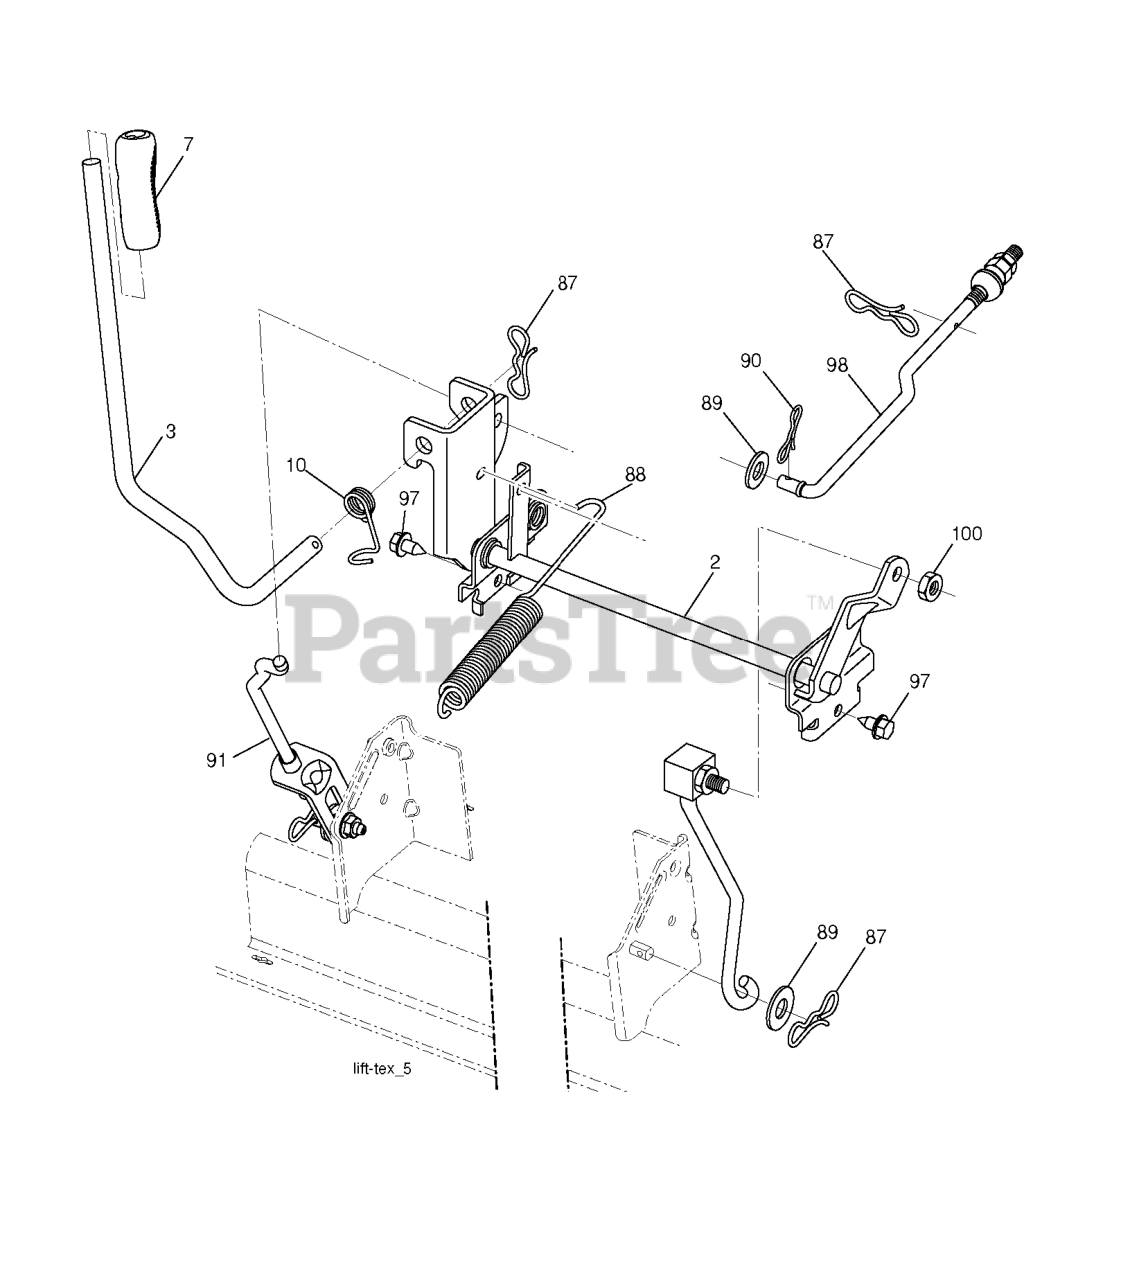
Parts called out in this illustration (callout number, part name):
2	SHAFT.ASM.LIFT.CROSS.H
3	LEVER.LIFT.HANDLE.LT
7	GRIP.HANDLE.LIFT.PVC.BLACK
10	SPRING.TORSION.LIFT.HANDLE
87	PIN.COTTER.7/16.BOW TI.
88	SPRING.LIFT.ASSIST
89	WASHER.CLEAR.ZINC
90	PIN.COTTER.5/16.BOW TI
91	LINK.ASM.LIFT.REAR
97	SCREW, 3/8-16X3/4
98	LINK.ASM.SUSP.FRONT.MW
100	LOCKNUT
